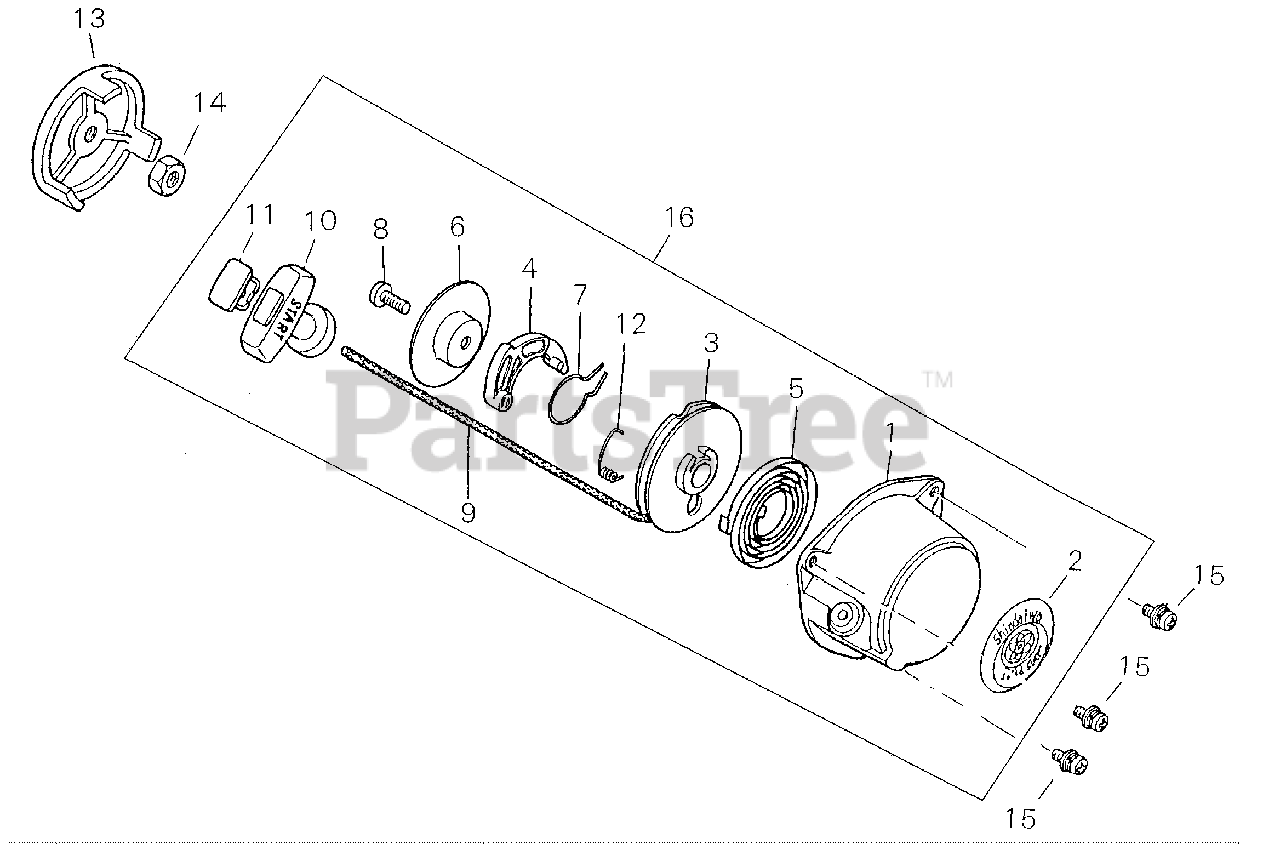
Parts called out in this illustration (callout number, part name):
1	CASE, RECOIL STARTER
2	LABEL, TRADE
3	REEL, ROPE
4	RATCHET
5	SPRING, RECOIL
6	PLATE, FRICTION
7	SPRING, FRICTION
8	SCREW
9	ROPE
10	GRIP, STARTER
11	CAP
12	SPRING, RETURN
13	PULLEY, STARTER
14	NUT M8×H5
15	BOLT M5×16
16	STARTER ASSY, RECOIL
